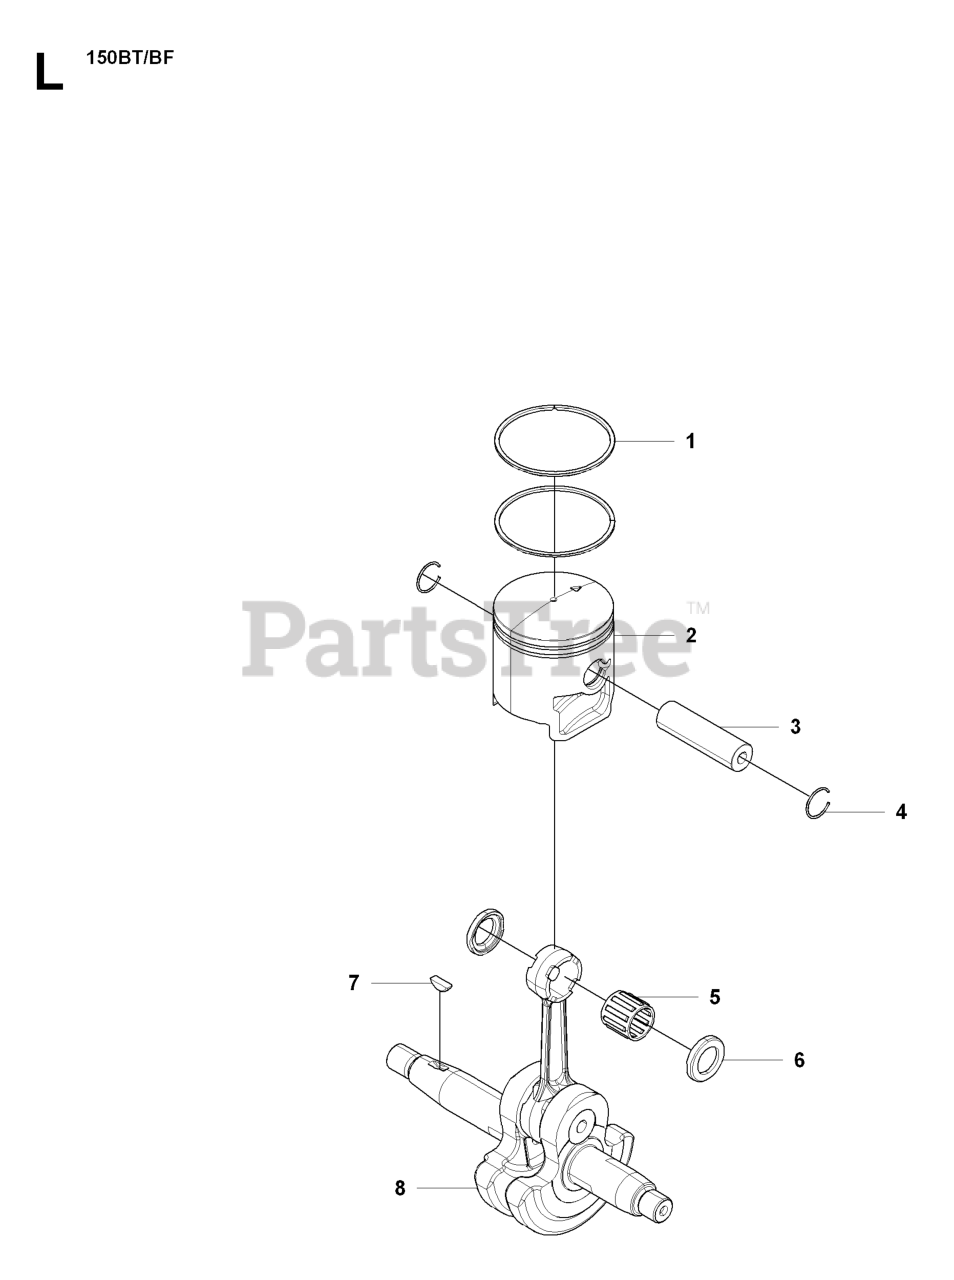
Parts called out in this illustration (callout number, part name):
1	PISTON RING
3	PISTON PIN
7	KEY
8	CRANKSHAFT
